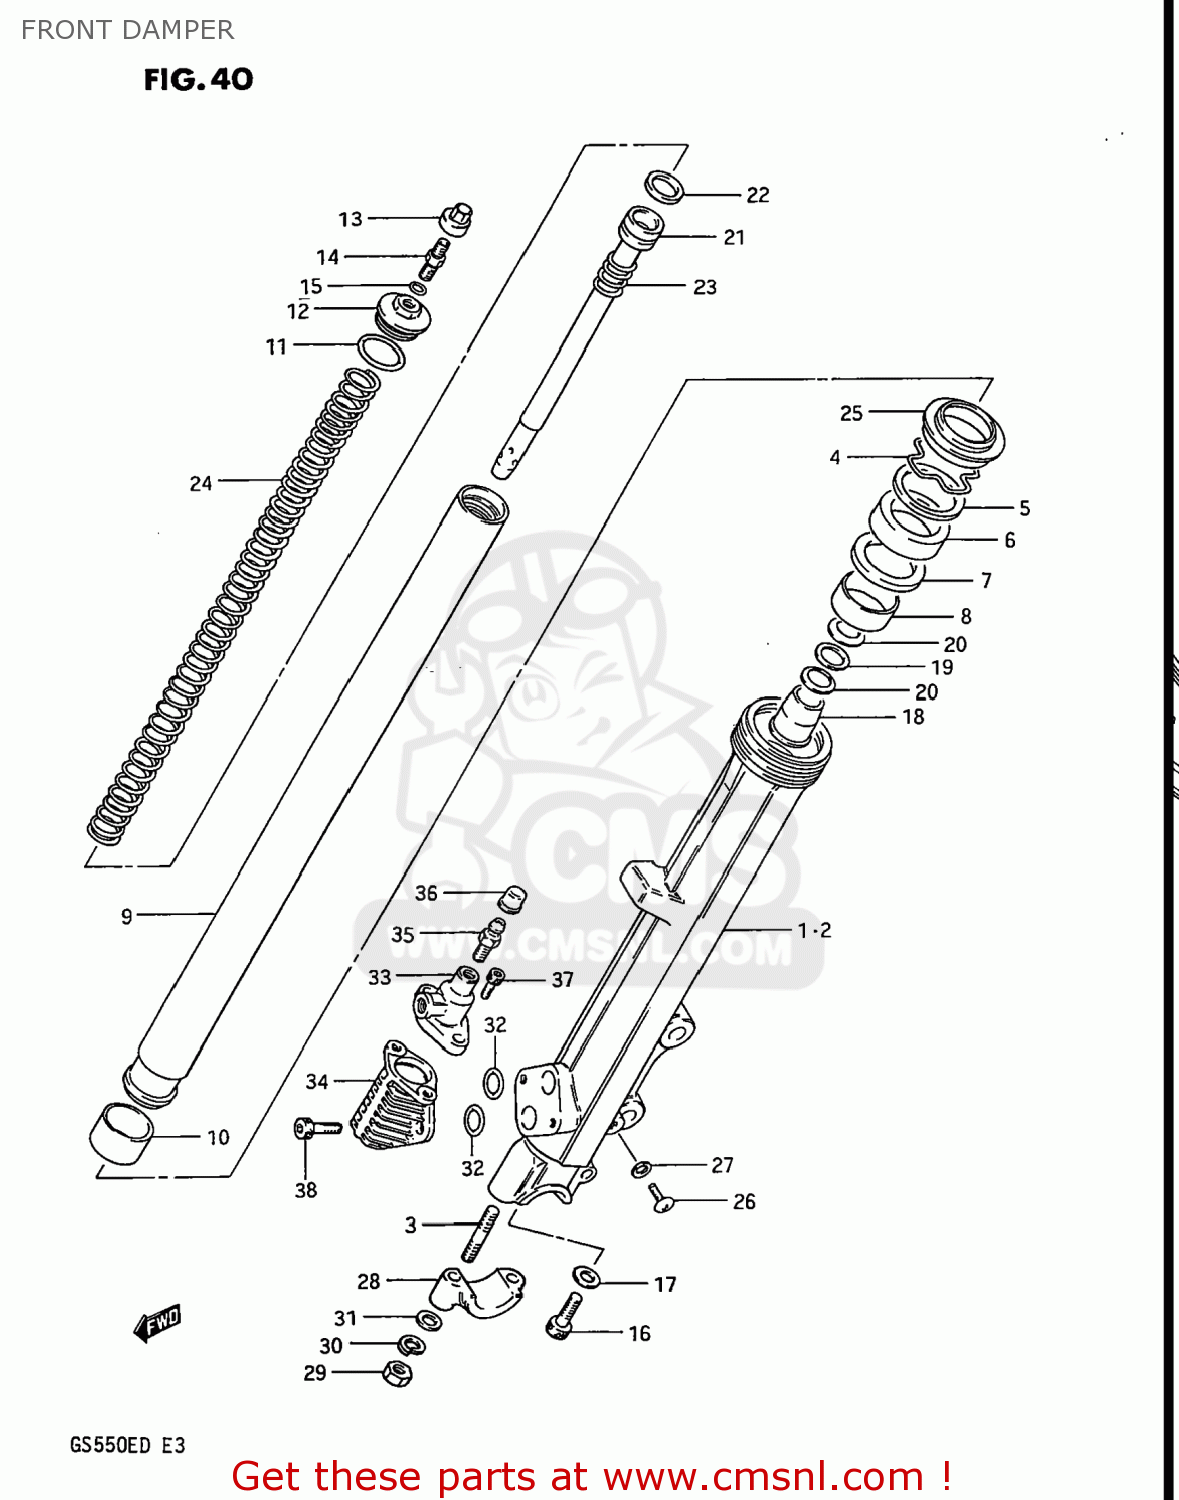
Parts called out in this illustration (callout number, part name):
1	TUBE,OUTER,RIGHT
2	TUBE,OUTER,LEFT
3	STUD 8X30
4	RING,STOPPER
5	WASHER. FRONT FORK
6	OIL SEAL,FRONT FORK
7	WASHER
8	METAL,SLIDE
9	TUBE,INNER
10	METAL,FRONT FORK PISTON
11	O RING
12	BOLT,FORK
13	CAP,FRONT FORK AIR VALVE
14	VALVE,FRONT FORK AIR
15	O-RING
16	BOLT,FORK CYLINDER(10X25)
17	GASKET (NAS)
18	PIECE,OIL LOCK
19	WASHER
20	SPRING,LEAF
21	CYLINDER,FRONT FORK
22	RING,PISTON
23	SPRING,REBOUND
24	SPRING
25	SEAL,DUST
26	SCREW
27	GASKET,DRAIN,PLUG (NAS)
28	HOLDER,AXLE
29	NUT
30	LOCK WASHER
31	WASHER,8.5X16X
32	O RING
33	PLUNGER SET
34	PDF ASSEMBLY
35	BREATHER,AIR
36	CAP,BREADER
37	BOLT
38	BOLT 6X16
